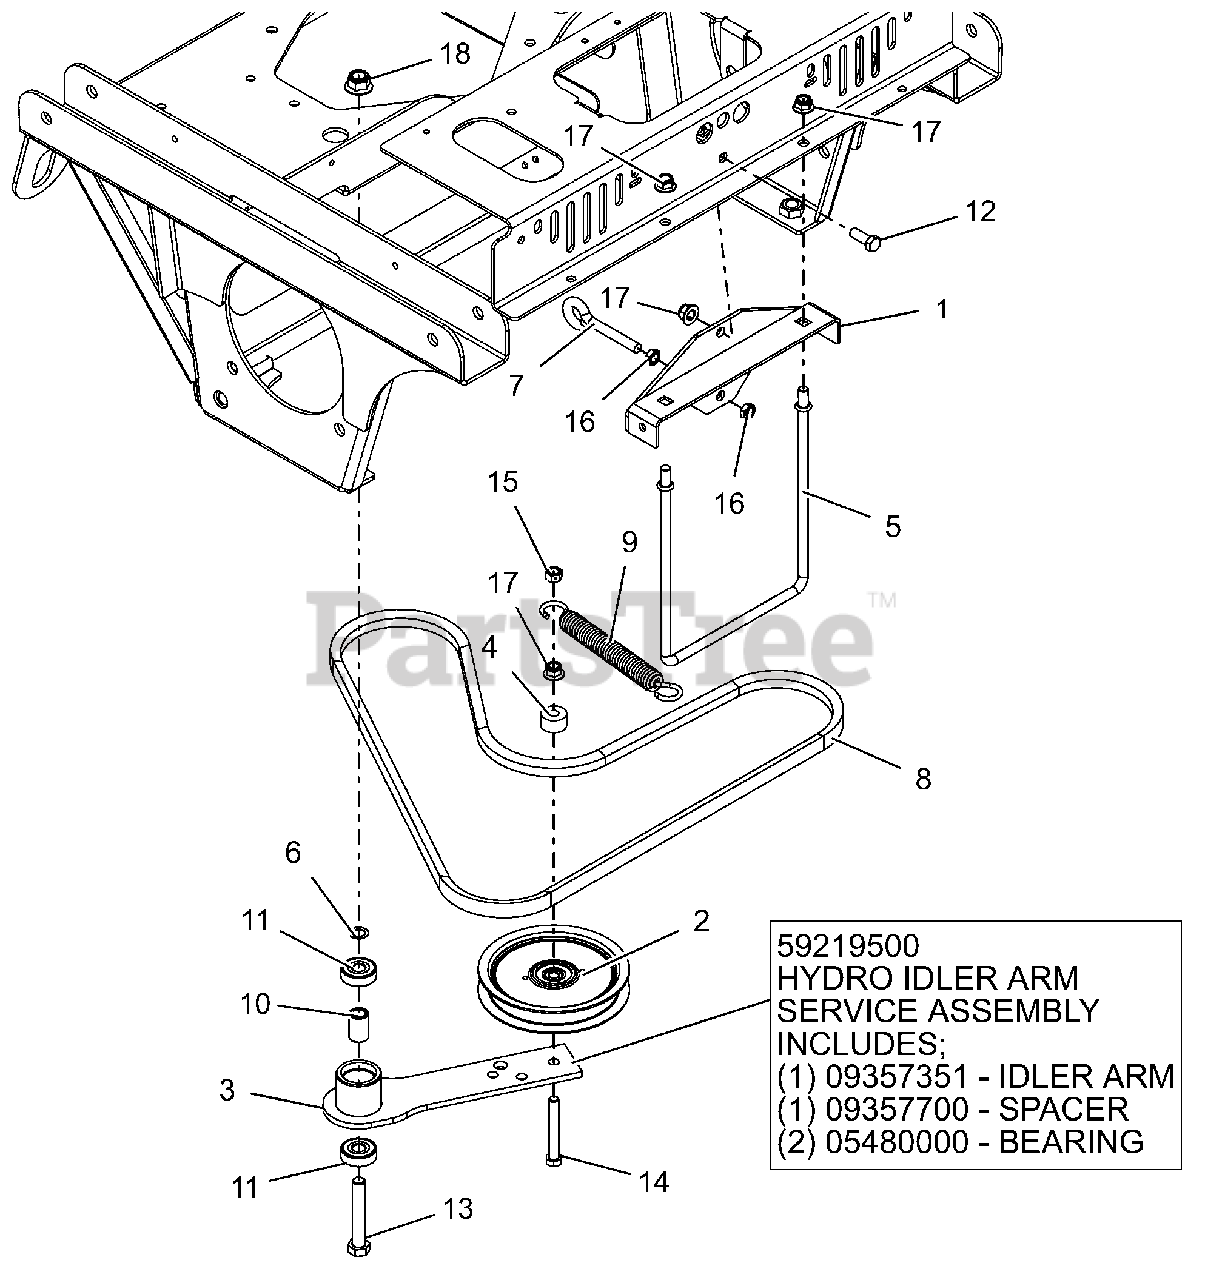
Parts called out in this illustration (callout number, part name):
1	SPRING ANCHOR BRKT WMT - BLACK
2	IDLER, FLAT-5.00X.75
3	HYDRO DRIVE IDLER ARM WMT- BLK
3	KIT, HYDRO IDLER ARM PT200/400
3	SPACER .510 X .75 X 1.1485
3	BRG-BALL .50X1.38X.438 SEALED
4	SPACER .390X1.000X.562
5	ROD, BRAKE MTG
6	WASHER, .500X.750X.020 THRUST
7	BLT-EYE .375-16X2.50 YWZC
8	V-BELT, COGGED B-RAW EDGE
9	SPRING, EXTENSION
10	SPACER .510 X .75 X 1.1485
11	BRG-BALL .500X1.38X.437
12	@BLT-HEX .38-16X1.00 GR5 YWZC
13	@BLT-HEX .50-13X3.00 GR5 YWZC
14	@BLT-HEX .38-16X2.75 GR5 YWZC
15	@NUT-LK-CTR .38-16 YWZC
16	NUT-HEX-JAM .375-16 YWZC
17	@NUT-LK-NYL-FLG .38-16 YWZC
18	@NUT-LK-NYL-FLG .50-13 YWZC
